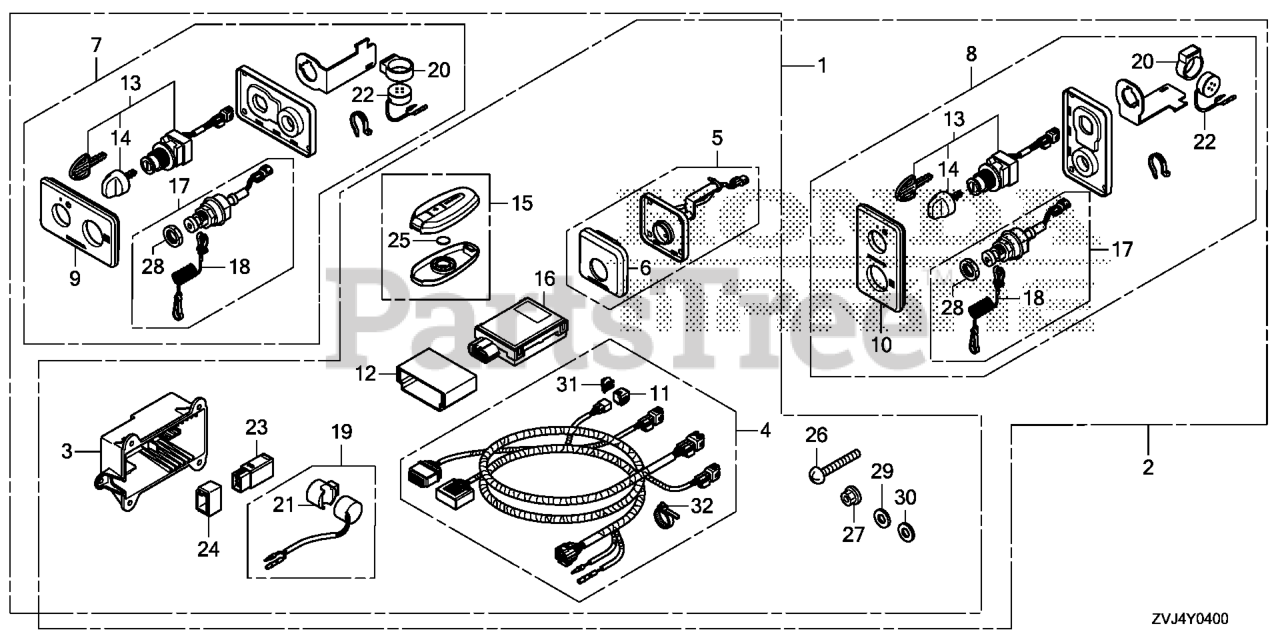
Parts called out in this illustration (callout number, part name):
1	UNIT KIT, SMART KEY
2	UNIT KIT, SMART KEY
3	CASE, CONTROL UNIT (SMART)
4	HARNESS ASSY., SMART KEY CONTROL
5	PANEL ASSY., START STOP (SINGLE)
6	PANEL, START STOP (SINGLE)
7	PANEL ASSY., KEY SWITCH (SMART)
8	PANEL ASSY., KEY SWITCH (SMART)
9	PANEL, KEY SWITCH
10	PANEL, KEY SWITCH
11	CAP, DUMMY (WPC 4P 090 M) (RED)
12	SUSPENSION, CONTROL UNIT (SMART)
13	SWITCH ASSY., COMBINATION (SMART)
14	KNOB
15	FOB ASSY. (315MHZ) (NOT AVAILABLE)
16	CONTROL UNIT, SMART (315MHZ)
17	SWITCH ASSY., EMERGENCY STOP
18	WIRE, EMERGENCY
19	BUZZER ASSY., WARNING
20	SUSPENSION, AUDIBLE PILOT
21	SUSPENSION, WARNING BUZZER
22	BUZZER, WARNING
23	RELAY ASSY., MAIN
24	SUSPENSION, RELAY
25	BATTERY (CR2025) (MSDS)
26	SCREW, PAN (5X40) DUAL QTY = (8) (SINGLE)
27	NUT, FLANGE (5MM)
28	NUT
29	WASHER, PLAIN (5MM)
30	WASHER, SPRING (5MM)
30	WASHER, SPG (5MM)
31	CLIP, CONNECTOR (DARK BROWN)
32	CLIP, HARNESS BAND (145MM) (BLACK)
